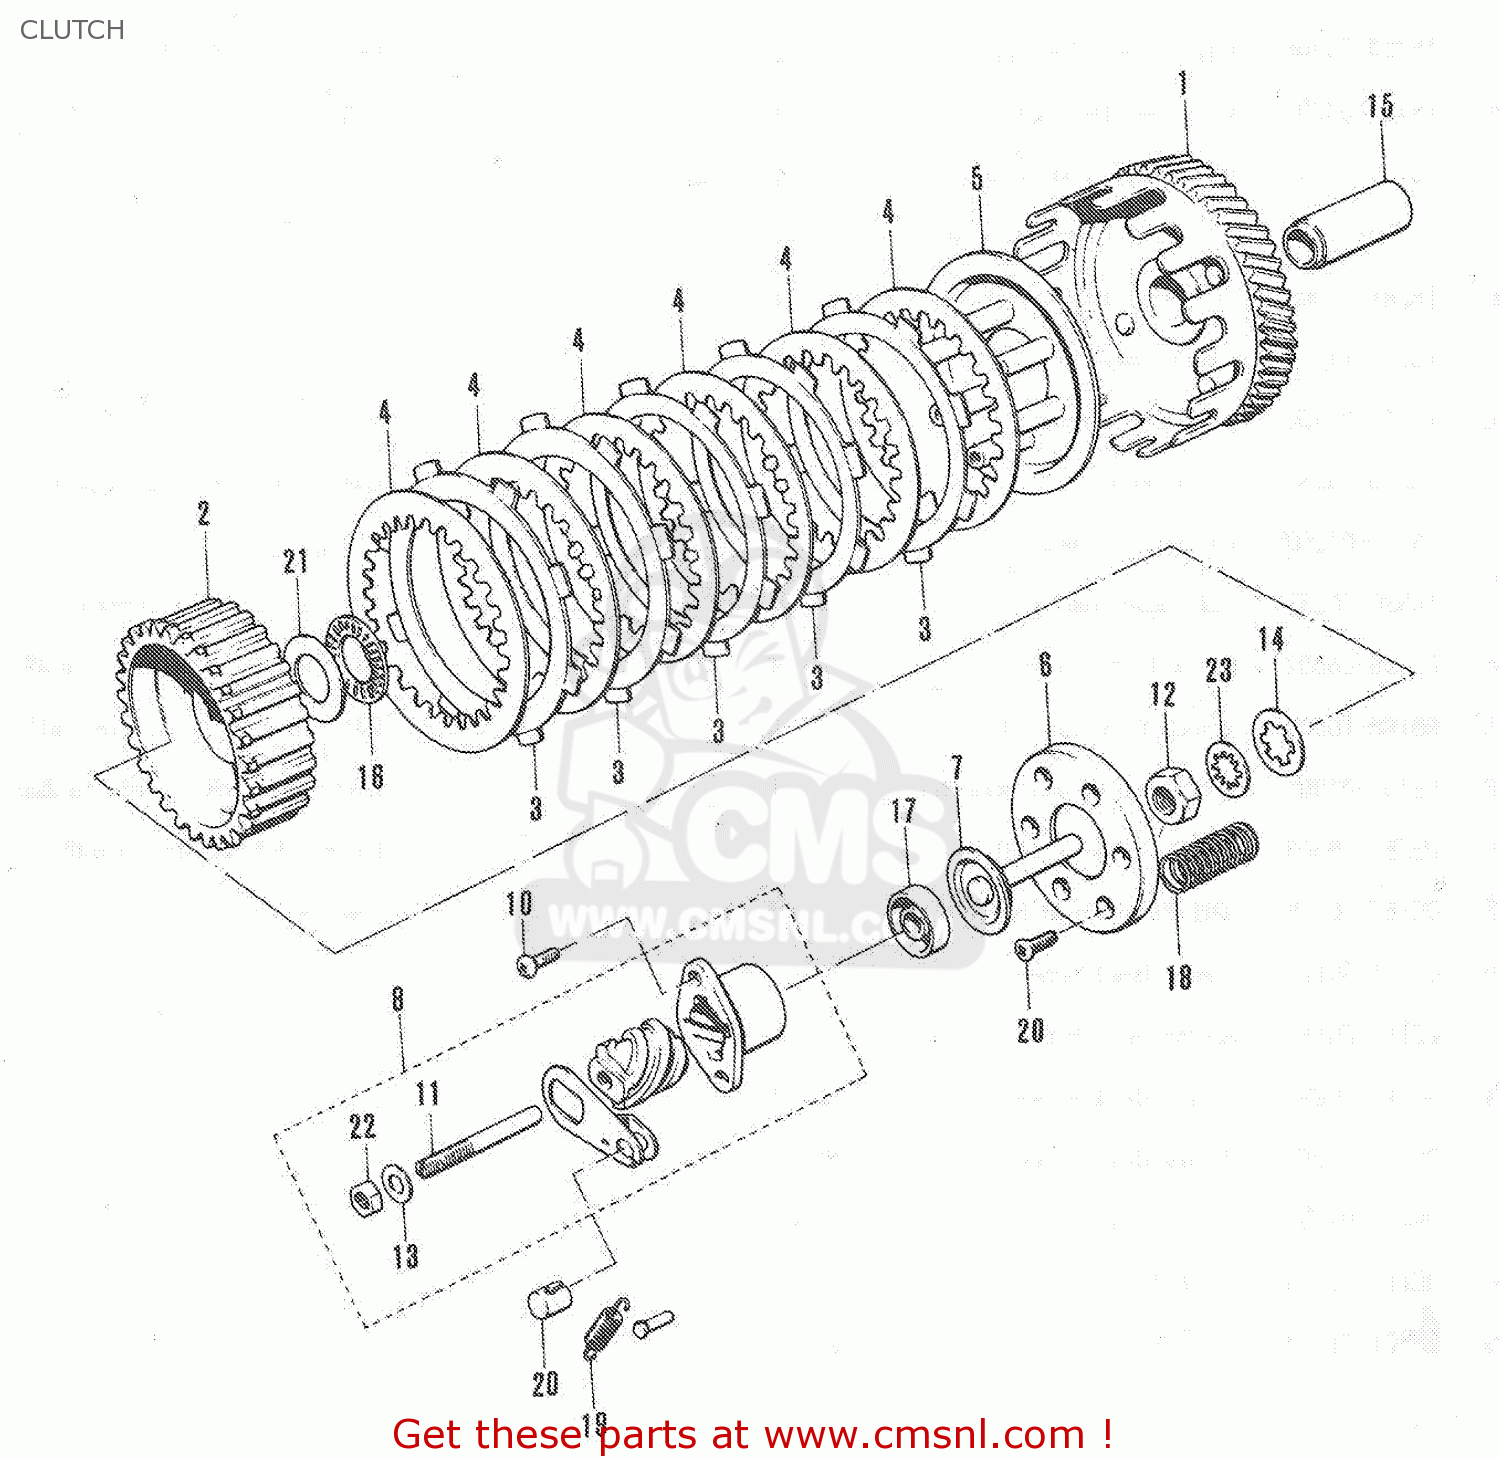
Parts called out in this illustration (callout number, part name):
1	GEAR ASSEMBLY,PRIMARY DRIVE
2	HUB,CLUTCH SLEEVE
3	PLATE,CLUTCH DRIVE (MCA)
4	PLATE,CLUTCH DRIVEN (NAS)
5	PLATE,CLUTCH PRESSURE
6	PLATE,CLUTCH OUTER
7	PIECE,CLUTCH PUSH
8	SCREW ASSY,CLUTCH RELEASE
9	PIECE,RELEASE ARM END
10	SCREW(5X14)
11	SCREW(6X47.5)
12	NUT
13	WASHER(6.5X16X1.2)
14	WASHER,LOCK
15	SPACER(17X21X55.4)
16	BEARING(20.1X35X2.8)
17	SEAL,OIL
18	SPRING
19	SPRING
20	SCREW
21	WASHER
22	NUT
23	WASHER,LOCK
